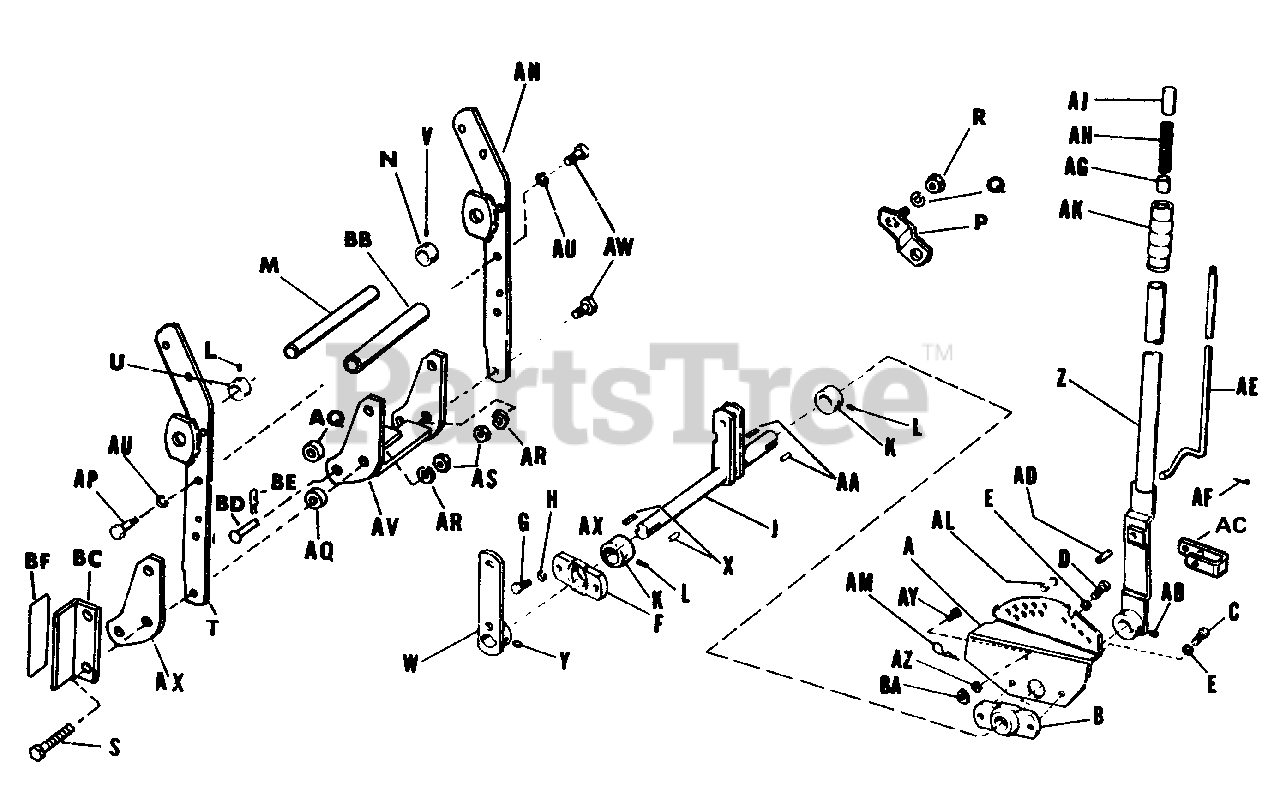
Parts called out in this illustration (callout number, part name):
A	Lift Lever Quadrant
B	Lift Lever Bearing
C	Hex. Cap Screw, 3/8"-16 x 7/8"
D	Hex. Cap Screw, 3/8"-16 x 1 1/4"
E	Lock Washer, 3/8"
F	Lift Lever Bearing
G	Hex. Cap Screw, 3/8"-16 x 7/8"
H	Lock Washer, 3/8"
J	Lift Shaft Assembly
K	Set Collar
L	Set Screw 5/16"-18x 5/16"
P	Pivot Bar Assy.
Q	Plain Washer
R	Hex. Nut, 3/8"-16
S	Hex. Cap Screw, 7/16"-14 x 2 1/2"
T	Arm Assembly
U	Set Collar
V	Set Screw, 5/16"-18 x l/2"
W	Front Lift Lever Assembly
Y	Set Screw, 5/16"-18 x 1/4"
Z	Lift Lever Assembly
AB	Set Screw, 5/16"-18 x 1/4"
AC	Lift Lever Latch
AE	Latch Rod
AF	Cotter Pin, 3/32" x 3/4"
AJ	Thumb Button
AK	Handle Grip
AM	Spring Clip
AN	Arm Assembly
AP	Hex. Cap Screw, 7/16"-14 x 1 3/4"
AR	Lock Washer
AS	Full Hex. Nut, 7/16"
AU	Lock Washer, 7/16"
AV	Draw Bar Assembly
AW	Hex. Cap Screw, 7/16"-14 x 1 1/4"
AY	Hex Cap Screw, 1/4"-20 x 5/8"
AZ	Lock Washer, 1/4"
BA	Hex Nut, 1/4"-20
BC	Plate, Decal
BD	Round Head Pin
BE	Spring Clip
BF	Film, Safety
